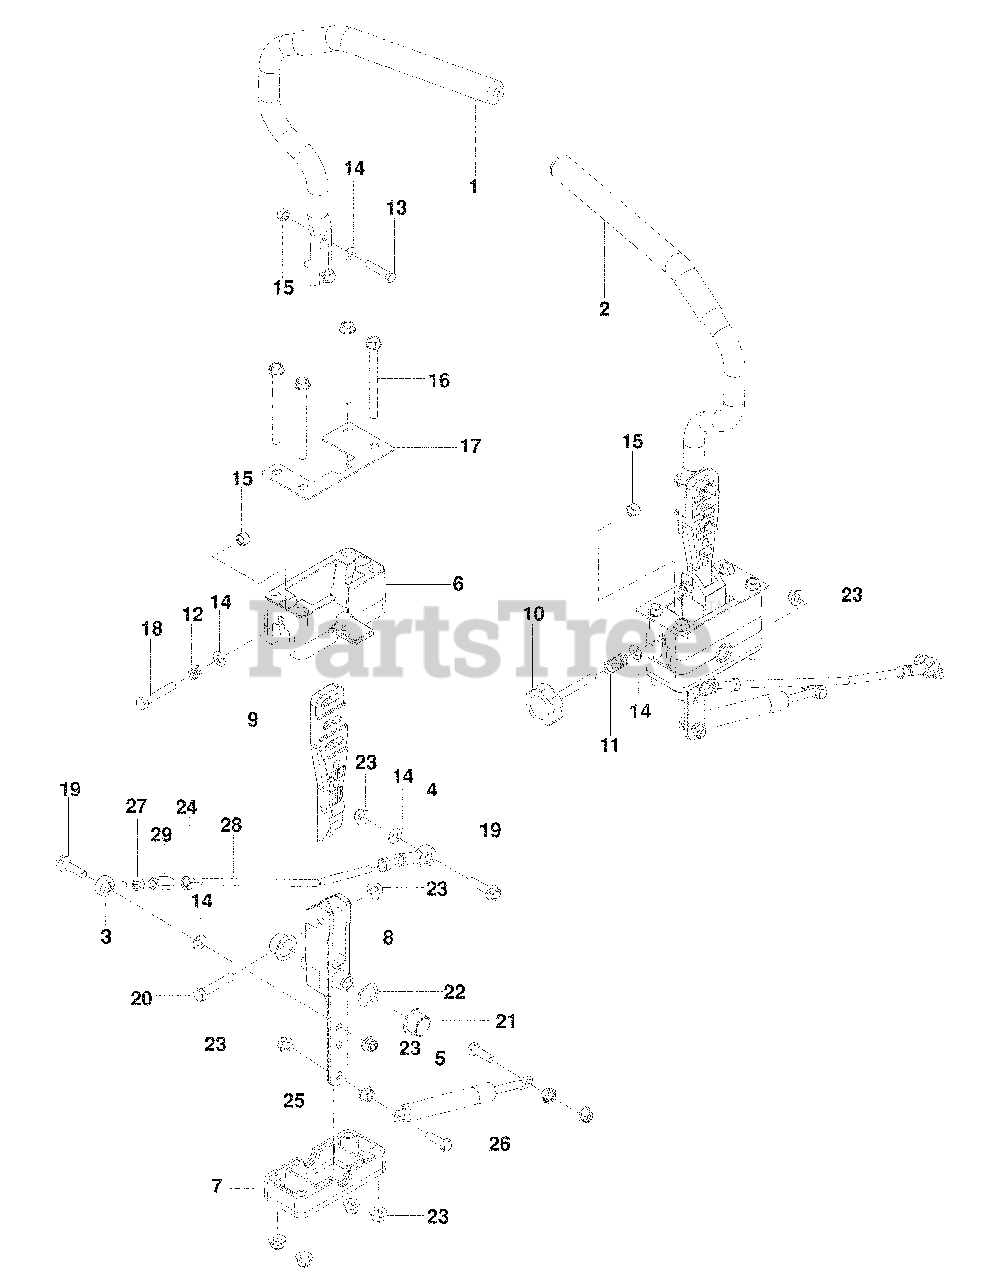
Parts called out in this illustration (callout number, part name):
1	LEVER, DRIVE w/ GRIP RT
2	LEVER, DRIVE w/ GRIP LT
3	ROD END LH
4	ROD END RH
6	BLOCK, UPPER
7	BLOCK, LOWER
8	PIVOT SECTION, DR CNTRL
9	MOUNT, DR CNTRL HANDLE
13	BOLT, HEX 5/16-18 x 1 ½
14	WASHER 5/16 SAE FLAT
15	NUT 5/16-18 HEX NYLOC
16	SCREW, HX FLG 5/16-18 x 3¾
17	PLATE, NEUTRAL STOP
18	BOLT 5/16-18 x 1¾ TPBLT
19	HHFS 5/16-18 x 1¼ TPBLT
20	BOLT, HEX 5/16-18 x 1¾
21	BEARING, FLANGE
22	WASHER .825, WAVE
23	NUT 5/16-18 FLANGE NYLOC
24	NUT 5/16-24 HEX
25	NUT 5/16-18 HEX WHIZLK
26	BOLT, HEX 5/16-18 x 1
27	NUT 5/16-24 HEX JAM LH
28	ROD, MOTION CONTROL
29	COUPLER, ROD END
